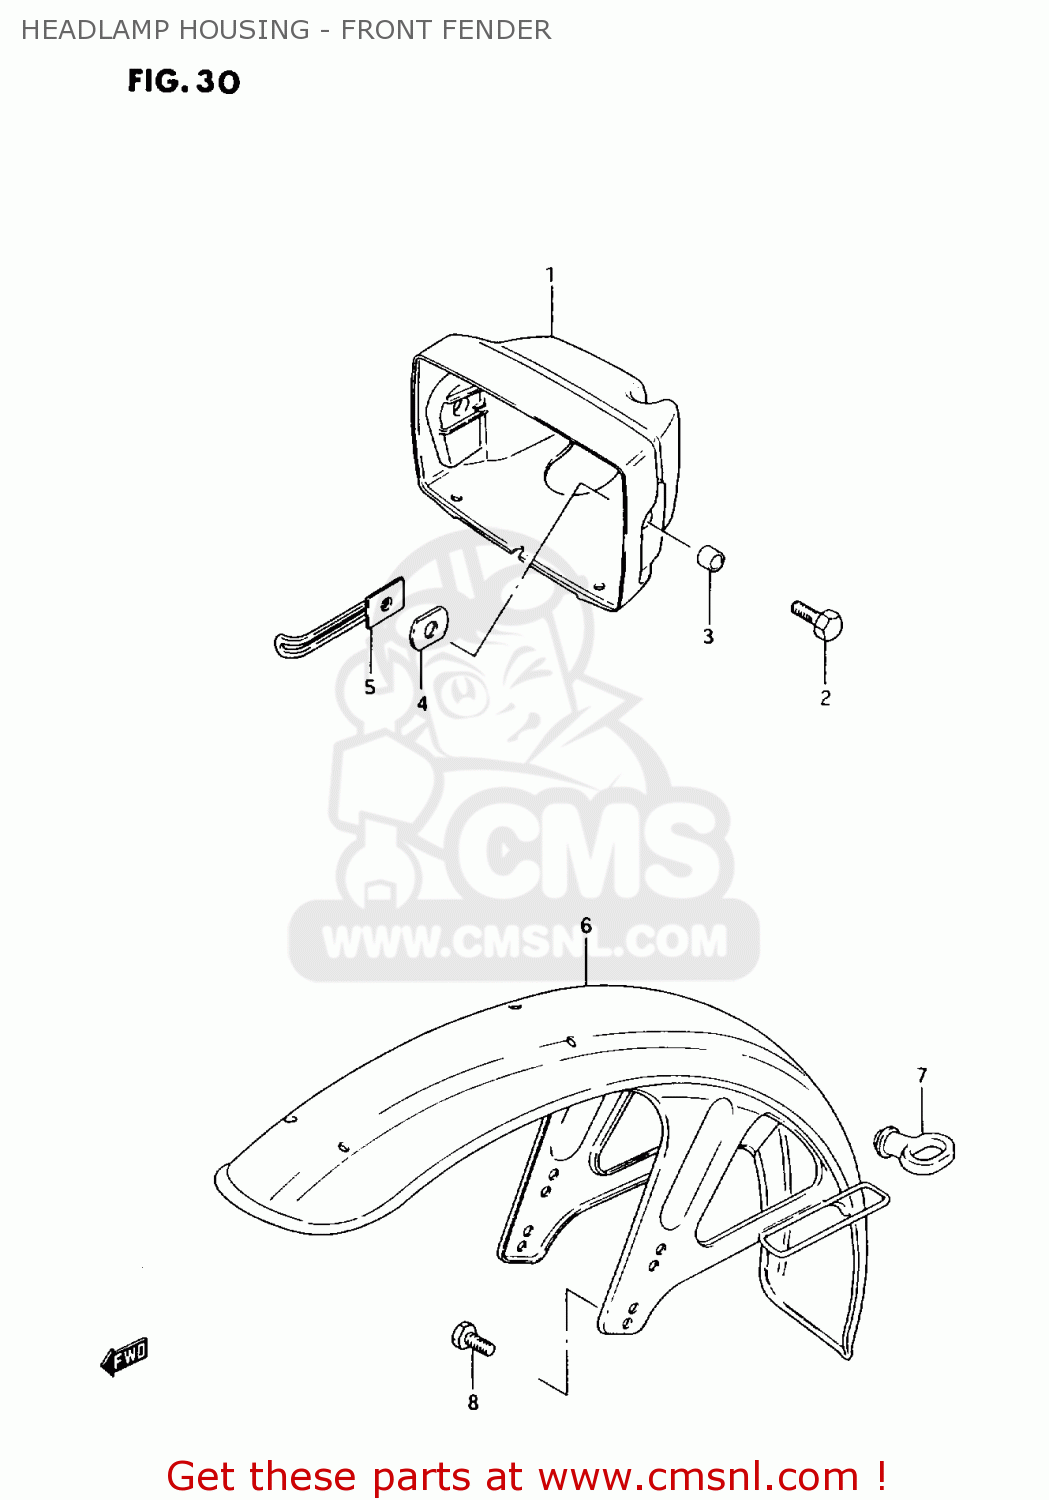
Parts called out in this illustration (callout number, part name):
1	HOUSING,HEADLAMP
2	BOLT
3	SPACER(8.5X12X7)
4	CUSHION
5	PLATE,HEADLAMP HOUSING
6	FENDER, FRONT
7	GUIDE,CABLE
8	BOLT
